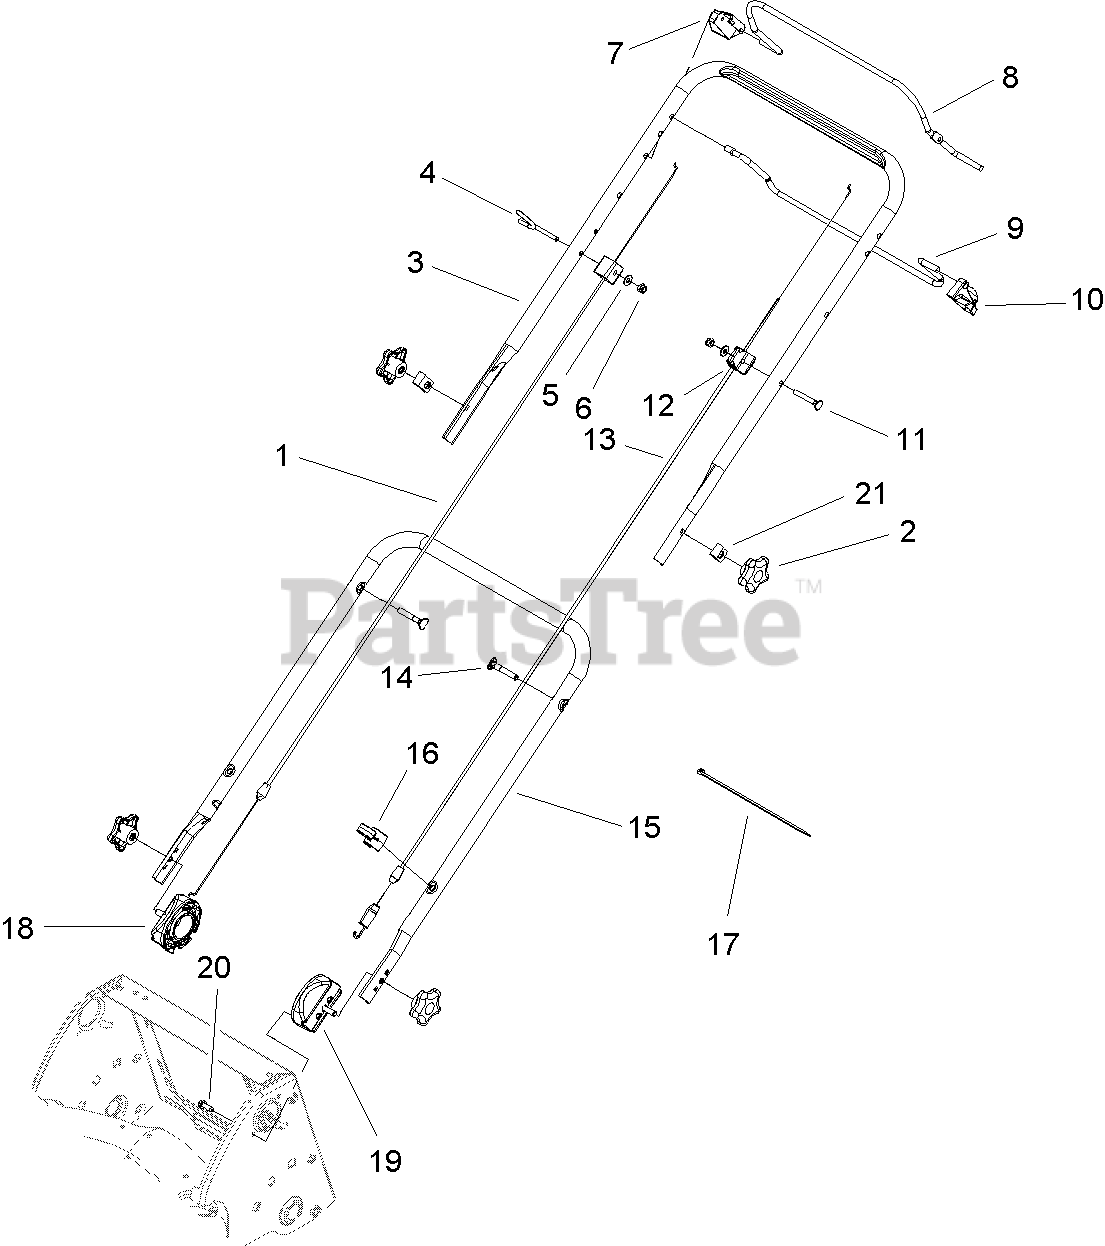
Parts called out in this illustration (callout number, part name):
1	Cable-Brake
2	KNOB-HANDLE
3	Handle-Upper
4	GUIDE-ROPE
5	WASHER-FLAT
6	NUT-LOCK, NI
7	STOP-PIVOT
9	Bail-Control
10	Stop-Pivot
12	ANCHOR-CABLE, UPPER
13	CABLE-TRACTION
14	SCREW-HANDLE
15	HANDLE-LOWER
16	Guide-Cable
17	STRAP-TIE
18	RH HANDLE MOUNT ASM
19	LH HANDLE MOUNT ASM
20	SCREW-HWHTF
